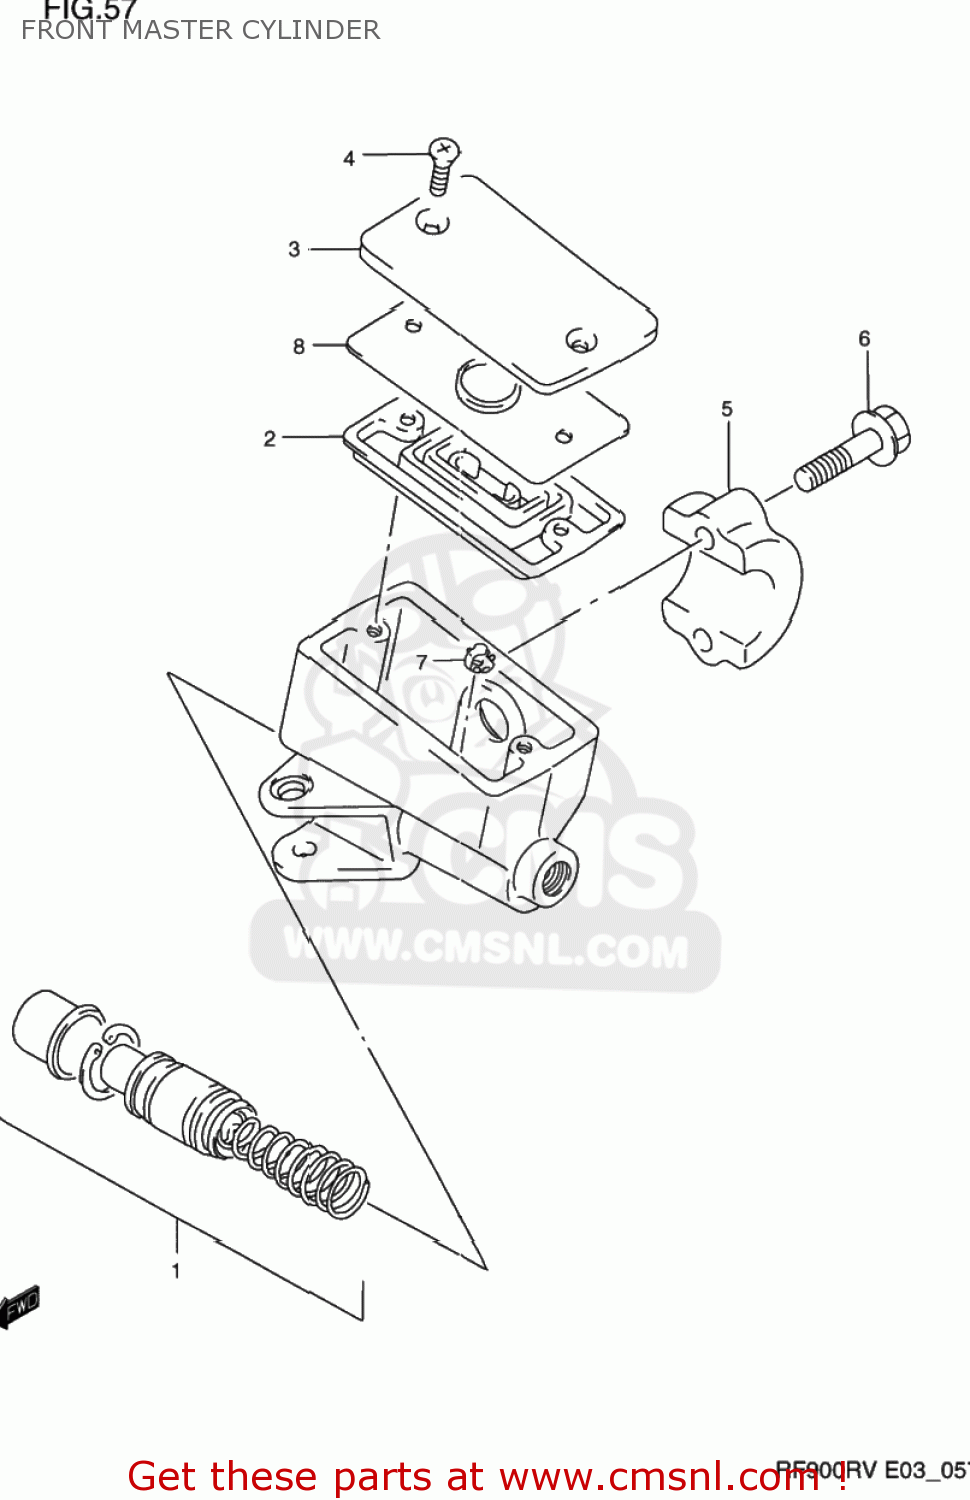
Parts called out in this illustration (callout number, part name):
1	PISTON & CUP SET
2	3
3	CAP
4	SCREW
5	HOLDER
6	BOLT(6X25)
7	PROTECTOR
8	PLATE,DIAPHRAGM
